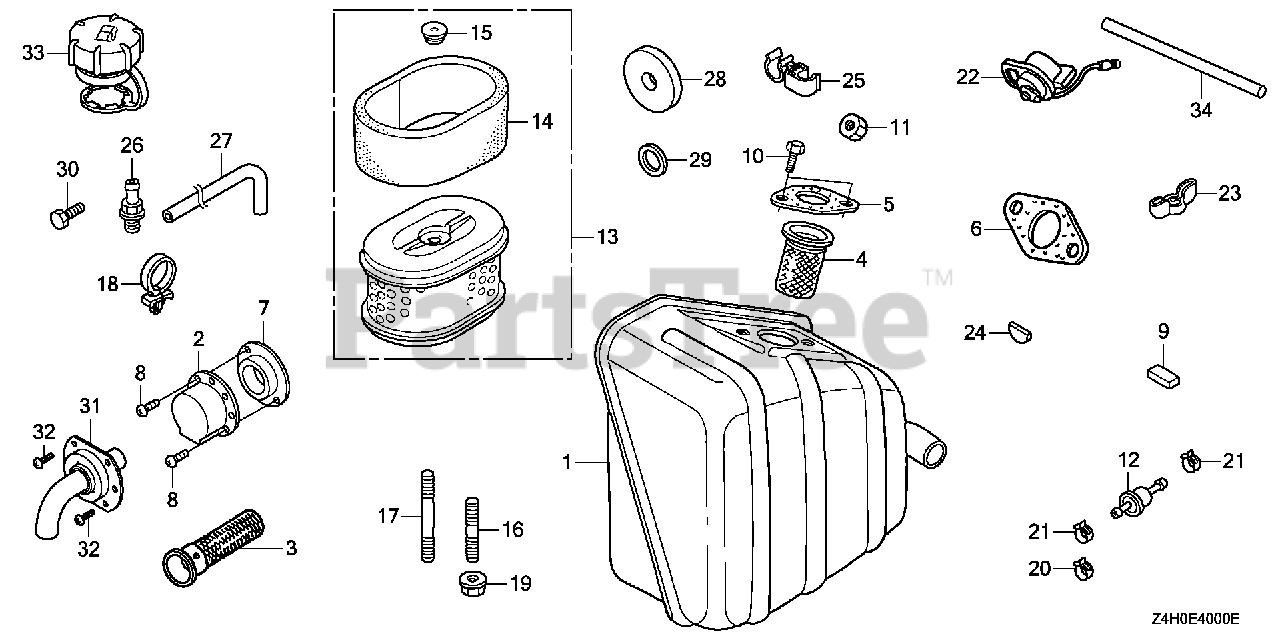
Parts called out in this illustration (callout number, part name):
2	CAP, MUFFLER
8	SCREW, TAPPING (4X6) (TO INSTALL OPTIONAL SPARK ARRESTER)
9	KEY (5X5X33)
